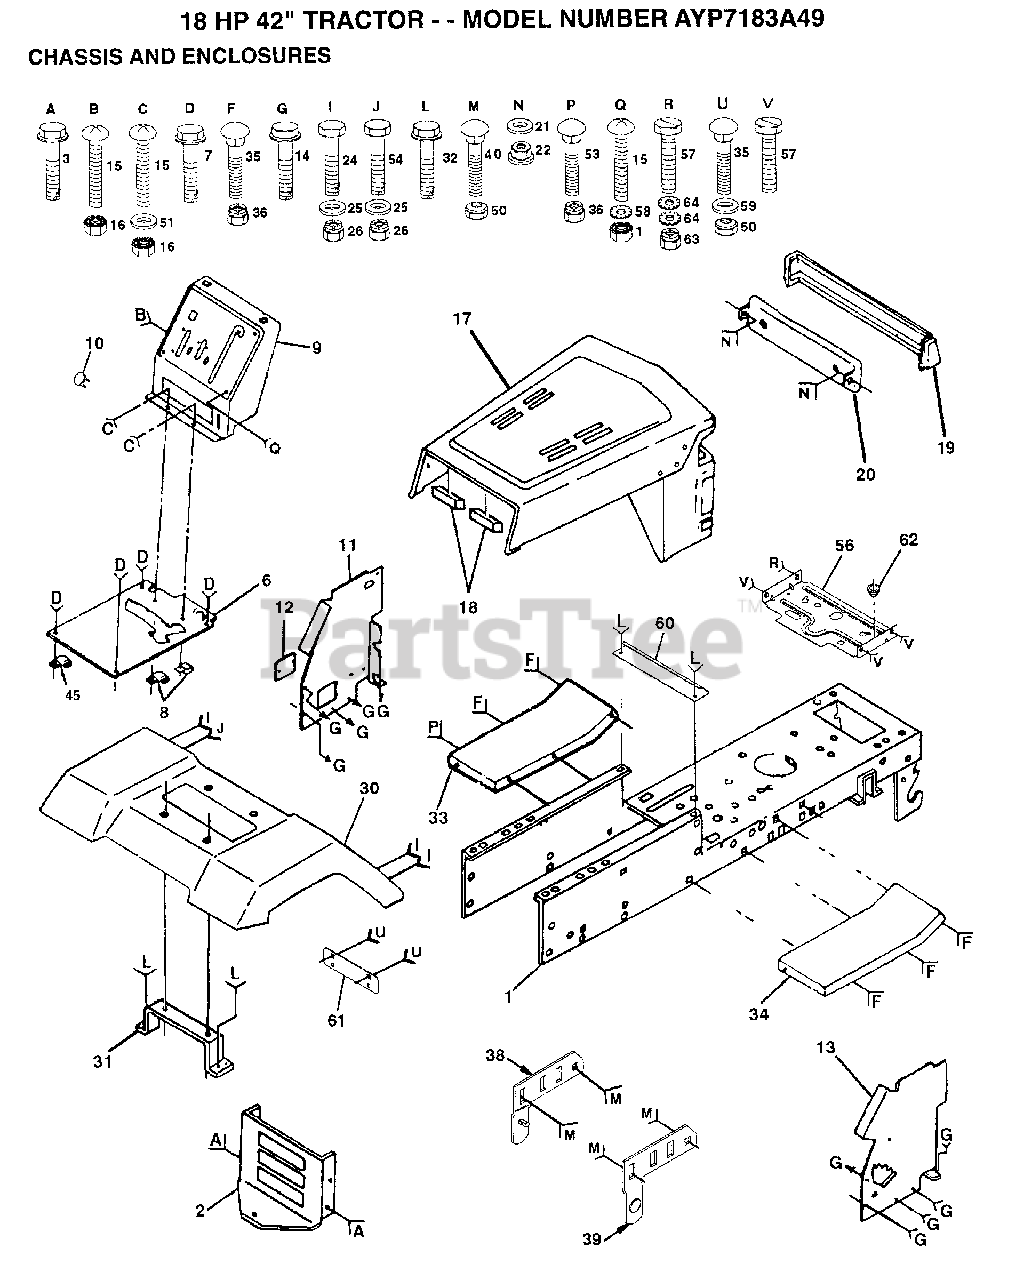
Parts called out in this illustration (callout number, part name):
3	SCREW
7	SCREW LT
8	CLIP T
9	DASH 1 PC SKSCND
10	PLUG BUTTON T
11	PANEL DASH LH
12	COVER ACCESS
14	SCREW LT
15	SCREW
17	HOOD/GRILLE ASM
21	WASHER PM
22	PAL NUT LT
25	WASHER
30	FENDER
31	BRACKET SUPT FEND
32	SCREW
33	FOOTREST LH
34	FOOTREST RH
35	BOLT
38	PIVOT BRKT LH
39	PIVOT BRKT RH
45	"CLIP,INSULATOR"
50	NUT
51	WASHER
56	PLATE MTG BTRY
57	SCREW
58	LOCKWASHER
60	SPACER FENDER LT
61	PLATE EXTEN FEND
64	LOCKWASHER.5/16.E
